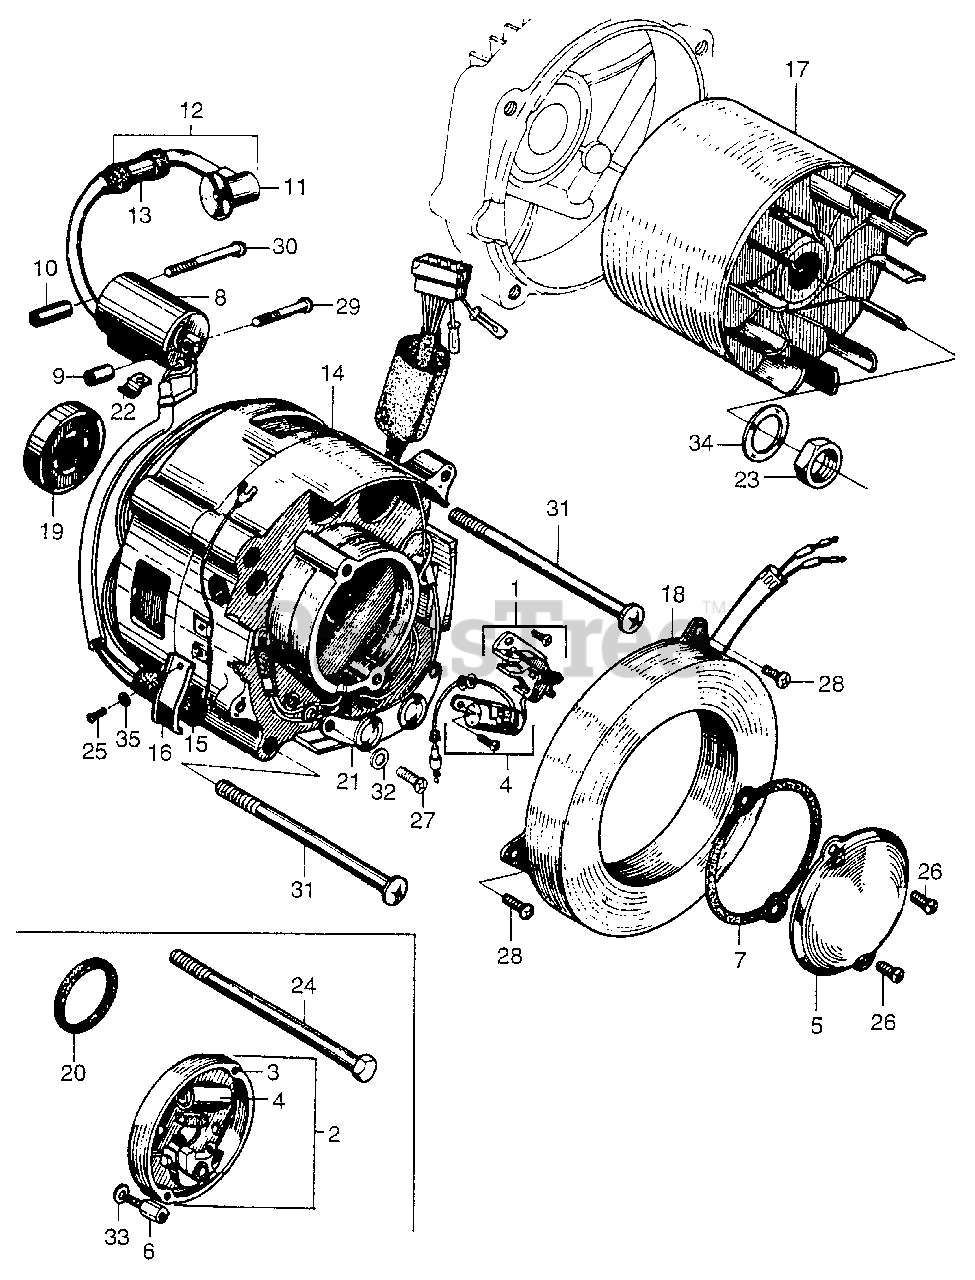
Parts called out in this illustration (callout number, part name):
1	POINTS ASSY., CONTACT (NOT AVAILABLE)
2	POINTS ASSY., CONTACT (NOT AVAILABLE)
3	BASE
4	CONDENSER ASSY. (NOT AVAILABLE)
5	COVER, POINTS (NOT AVAILABLE)
5	COVER, POINTS
6	BOLT, POINTS SET
6	SCREW, PAN (5X12)
8	COIL ASSY., A.C. IGNITION (NOT AVAILABLE)
9	COLLAR A, IGNITION DISTANCE (NOT AVAILABLE)
10	COLLAR B, IGNITION DISTANCE
11	COVER, IGNITION TERMINAL (NOT AVAILABLE)
12	TERMINAL ASSY., IGNITION (NOT AVAILABLE)
12	TERMINAL ASSY., IGNITION
13	SUPPRESSOR, NOISE (NOT AVAILABLE)
14	STATOR ASSY., ALTERNATOR
15	TUBE A, RUBBER
16	CLAMP, JOINT
17	ROTOR, ALTERNATOR
18	REACTOR
19	BEARING, NEEDLE
19	BEARING, RADIAL BALL (6001UU) (SOURCE: VINTAGE PARTS INC.)
20	OIL SEAL
21	RECTIFIER, SILICON
22	CLAMP, WIRE
23	NUT, SPECIAL (16MM)
24	BOLT, HEX. (6X103) (SOURCE: VINTAGE PARTS INC.)
24	BOLT, HEX. (6X145) (SOURCE: VINTAGE PARTS INC.)
25	SCREW, PAN (4X6)
26	SCREW, PAN (4X6)
27	SCREW, PAN (4X20)
28	SCREW, PAN (5X8)
29	SCREW, PAN (5X30)
30	SCREW, PAN (5X42) (NOT AVAILABLE)
32	WASHER, PLAIN (4MM)
33	WASHER, PLAIN (6MM)
34	WASHER, FLAT (16MM)
35	WASHER, SPRING (4MM)
